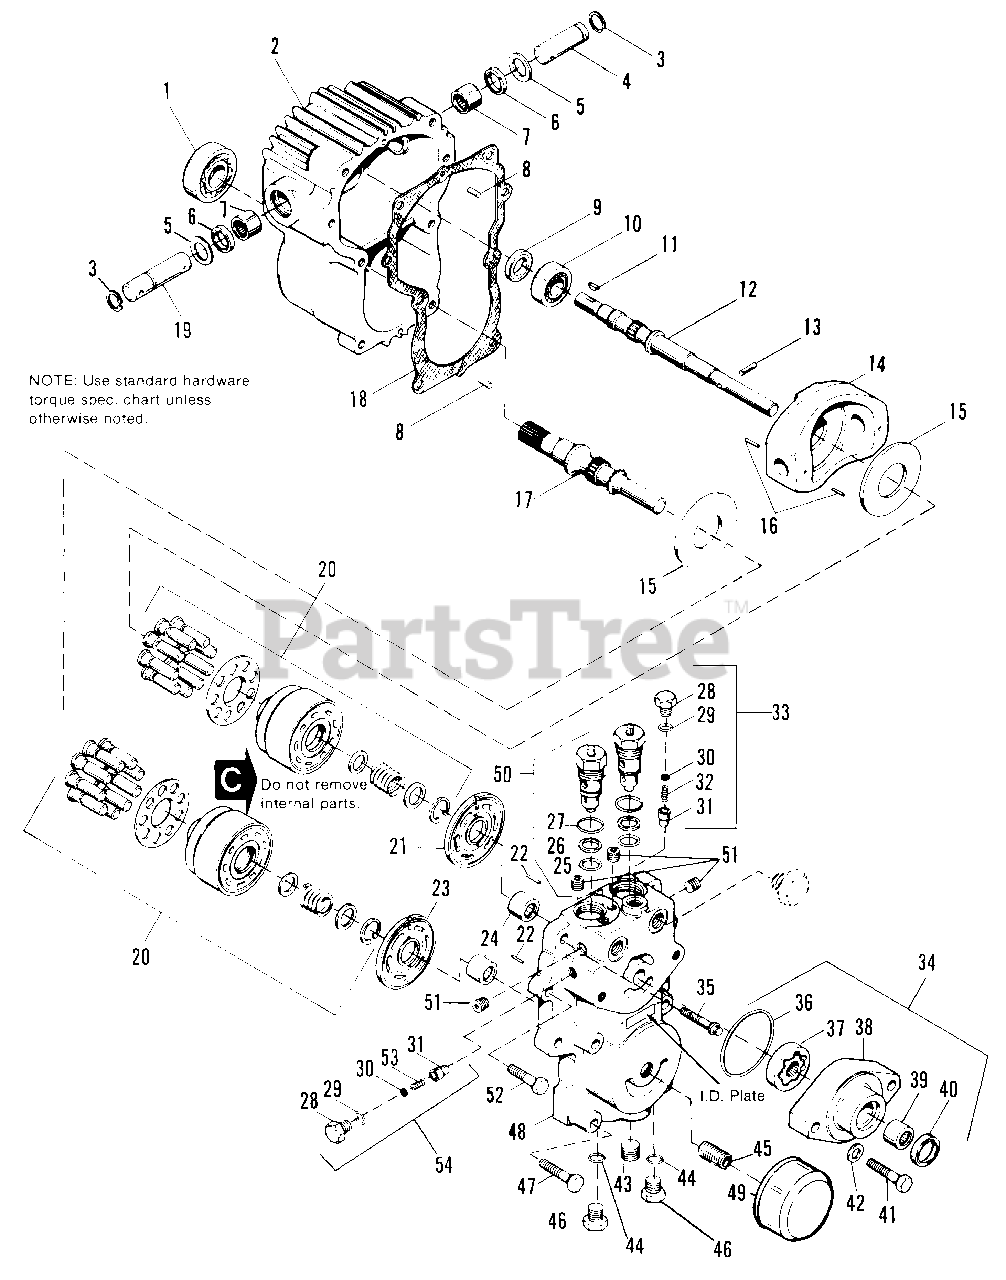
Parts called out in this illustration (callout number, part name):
1	BEARING, Ball
3	RING, Retainer
5	WASHER, Special
7	BEARING, Needle
8	PIN, Headless, Straight
10	BEARING, Ball
11	KEY, Woodruff
12	SHAFT, Pump
13	PIN, Headless
14	PLATE, Swash
15	PLATE, Thrust
16	PIN, Spring, Coiled
17	SHAFT, Motor
20	CYLINDER BLOCK KIT
21	PLATE, Valve, Pump
22	PIN, Straight
23	PLATE, Valve, Motor
24	BEARING, Needle
26	RING, Backup
28	PLUG, Hex Hd.
31	CONE, Relief Valve
32	SPRING, Relief Valve
33	RELIEF VALVE KIT (Incl. Ref. Nos. 28-32)
34	CHARGE PUMP KIT (Incl. Ref. Nos. 36-40)
35	CAPSCREW, 12 pt.
39	BEARING, Needle
41	CAPSCREW, 7/16-14 x 2
42	WASHER, Flat
45	UNION, Filter
46	PLUG, Hex Hd.
47	CAPSCREW, 3/8-16 x 2
48	SECTION, Center
49	FILTER (Short Canister) 25 Micron
50	CHECK VALVE (Incl. Ref. Nos. 25, 26 & 27)
52	CAPSCREW, 3/8-16 x 1-1/4
53	SPRING, Relief
54	RELIEF VALVE KIT (Incl. Nos. 28-31, 53)
